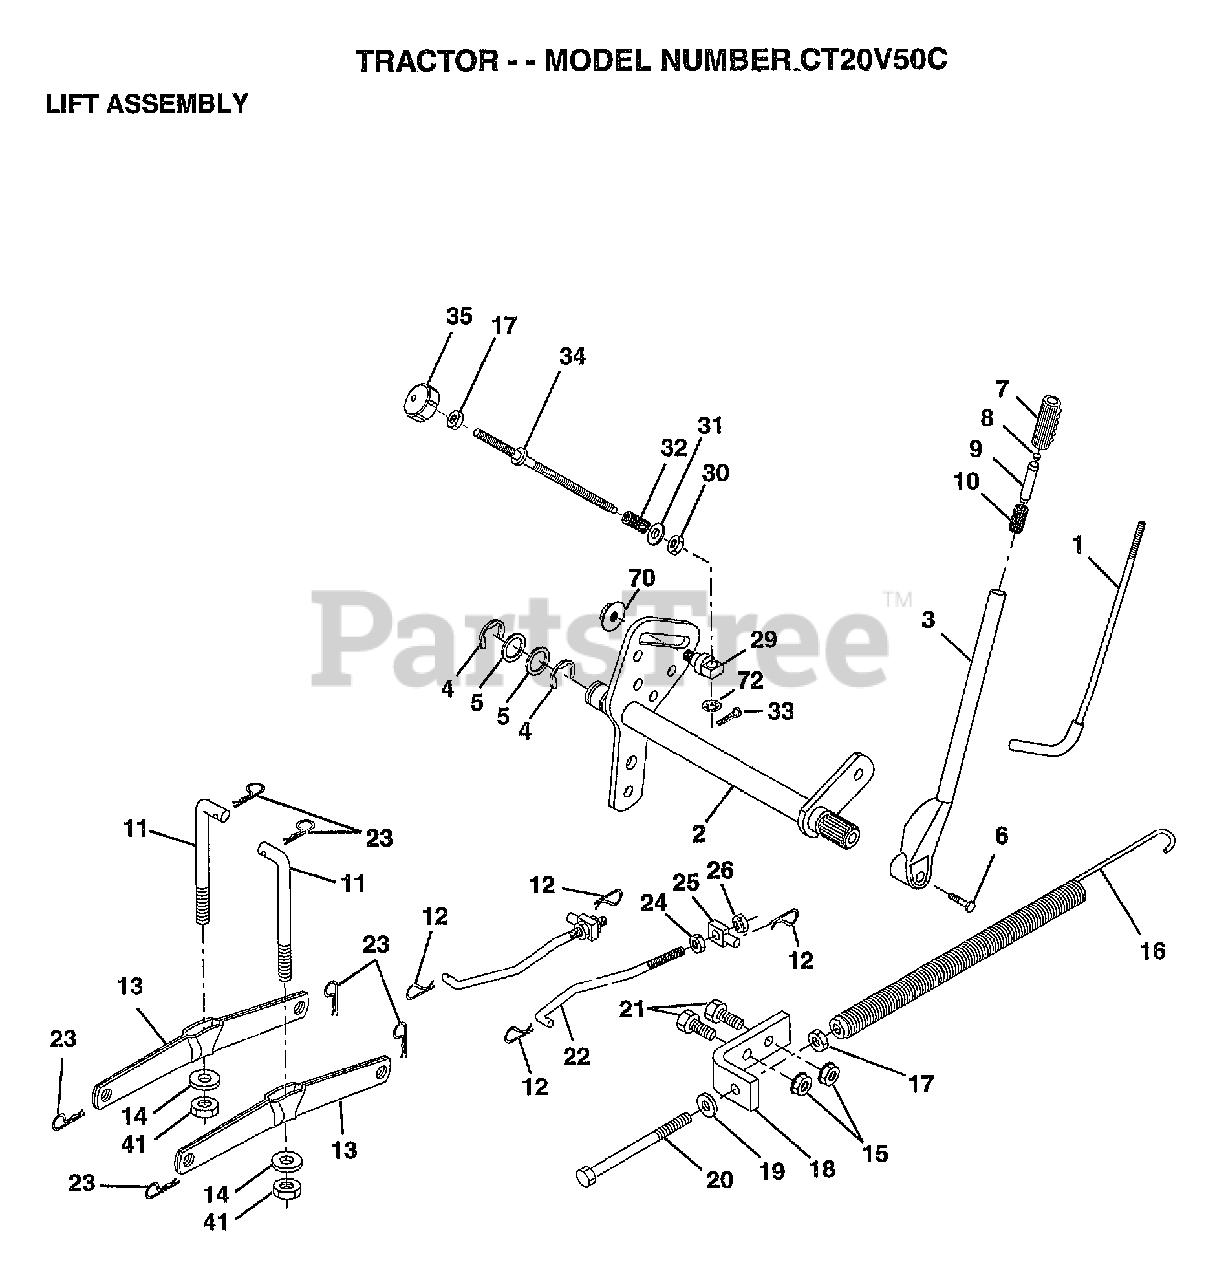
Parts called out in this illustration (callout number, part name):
1	LEVER ROD LT
2	SHAFT AMS LIFT
4	E-RING
5	WASHER
6	"BOLT,HEX"
7	GRIP
10	SPRING T
11	LINK.LIFT.MWR.VGT
12	RETAINER.SPRING
13	ARM SUSP REAR
14	BEARING PVT LH
17	NUT
18	BRACKET SPRING AS
19	WASHER
20	BOLT-ADJ SPRING T
21	BOLT
22	LINK.FRONT
24	NUT
25	TRUNION
26	NUT.LK.W/WSH.1/2.
29	TRUNNION
30	NUT T
31	WASHER
32	SPRING.COMP.INF.H
34	ROD.ADJ.LIFT
35	KNOB INF 3/8-16
41	NUT.CROWNLOCK.3/8
70	NUT.HXFLG.LOCK.
72	NUT PUSH M
